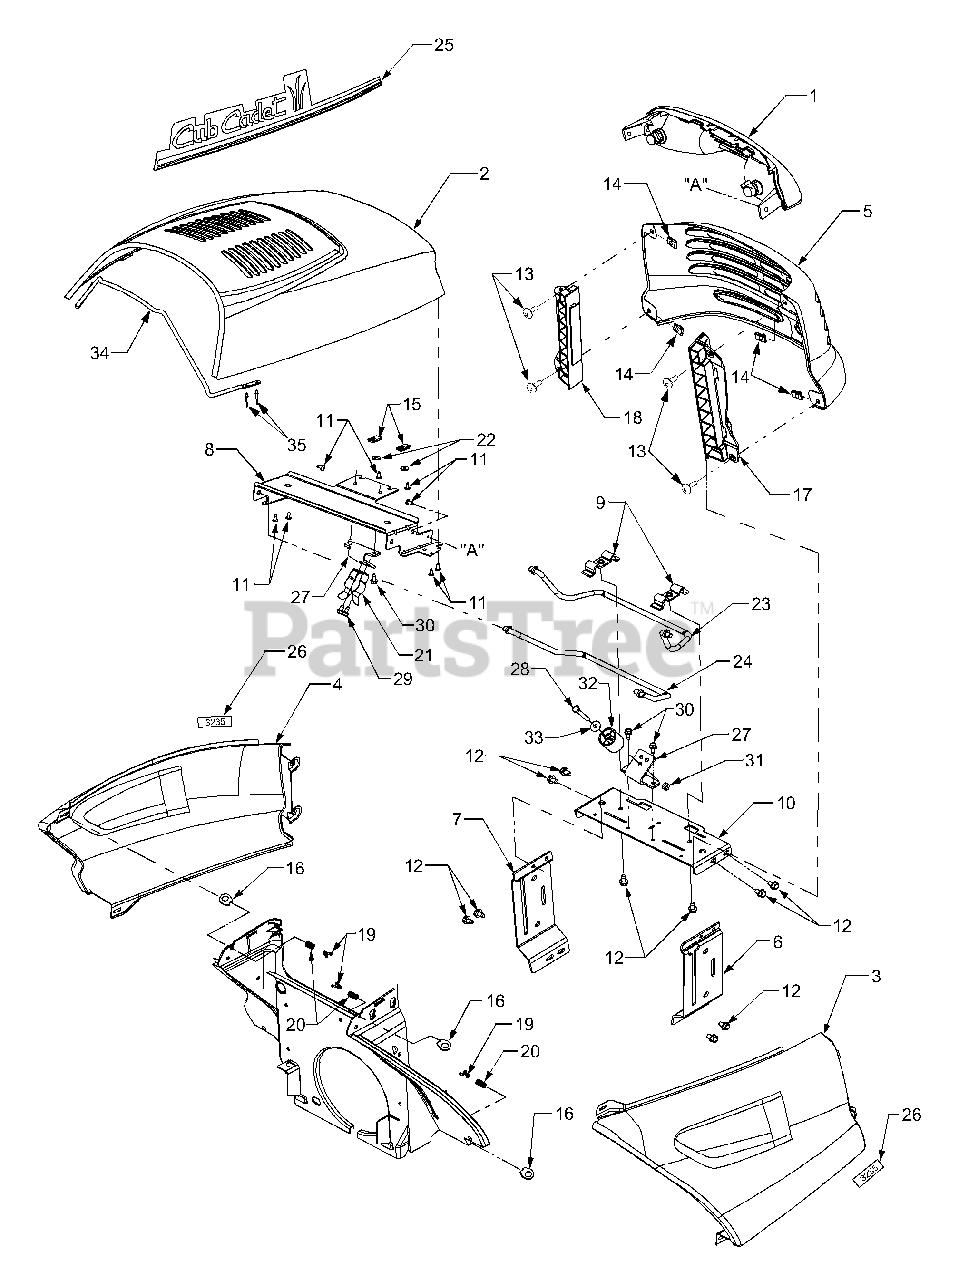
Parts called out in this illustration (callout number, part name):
1	Headlight Assembly
3	Side Panel, RH
4	Side Panel, LH
5	Grille, Series 3000
6	Support, Grille - RH
7	Support, Grille - LH
8	Bracket, Upper Hood
9	Bracket, Rod Retainer
10	Support, Hood
11	Screw, Truss Hd, Tapp, #10-16 x .5
12	Screw, Hex Wash. Hd. Tapp 5/16-18 x .5
13	Screw, Phil. Pan Hd. 1/4-20 x .75
14	Nut, U Type Speed, 1/4-20
15	Nut, U-type Speed, #10
16	Latch, 1/4 Turn
17	Mount, Side Panel/Grille RH
18	Mount, Side Panel/Grille LH
19	Clip, Spring
20	Spring, Compression
21	Spring, Hood Latch
22	Washer, Flat, .194 x .62 x .063
23	Rod, Upper Hood
24	Rod, Lower Hood
25	Graphic, Hood - RH
26	Graphic, 3235
27	Bracket, Hood Latch Support
28	Screw, Hex Cap, 1/4-20 x 1.75 GR5
29	Screw, Hex Wash Hd Tapp, 1/4-20 x .5
30	Screw, Hex Wash Hd Tapp, 1/4-14 x .5
31	Nut, Hex Top Lock, 1/4-20
32	Roller, Hood Latch
33	Washer, Flat, .283 x .75 x .030
34	Rod, Hood Support
35	Rivet, Pop, .125 OD
